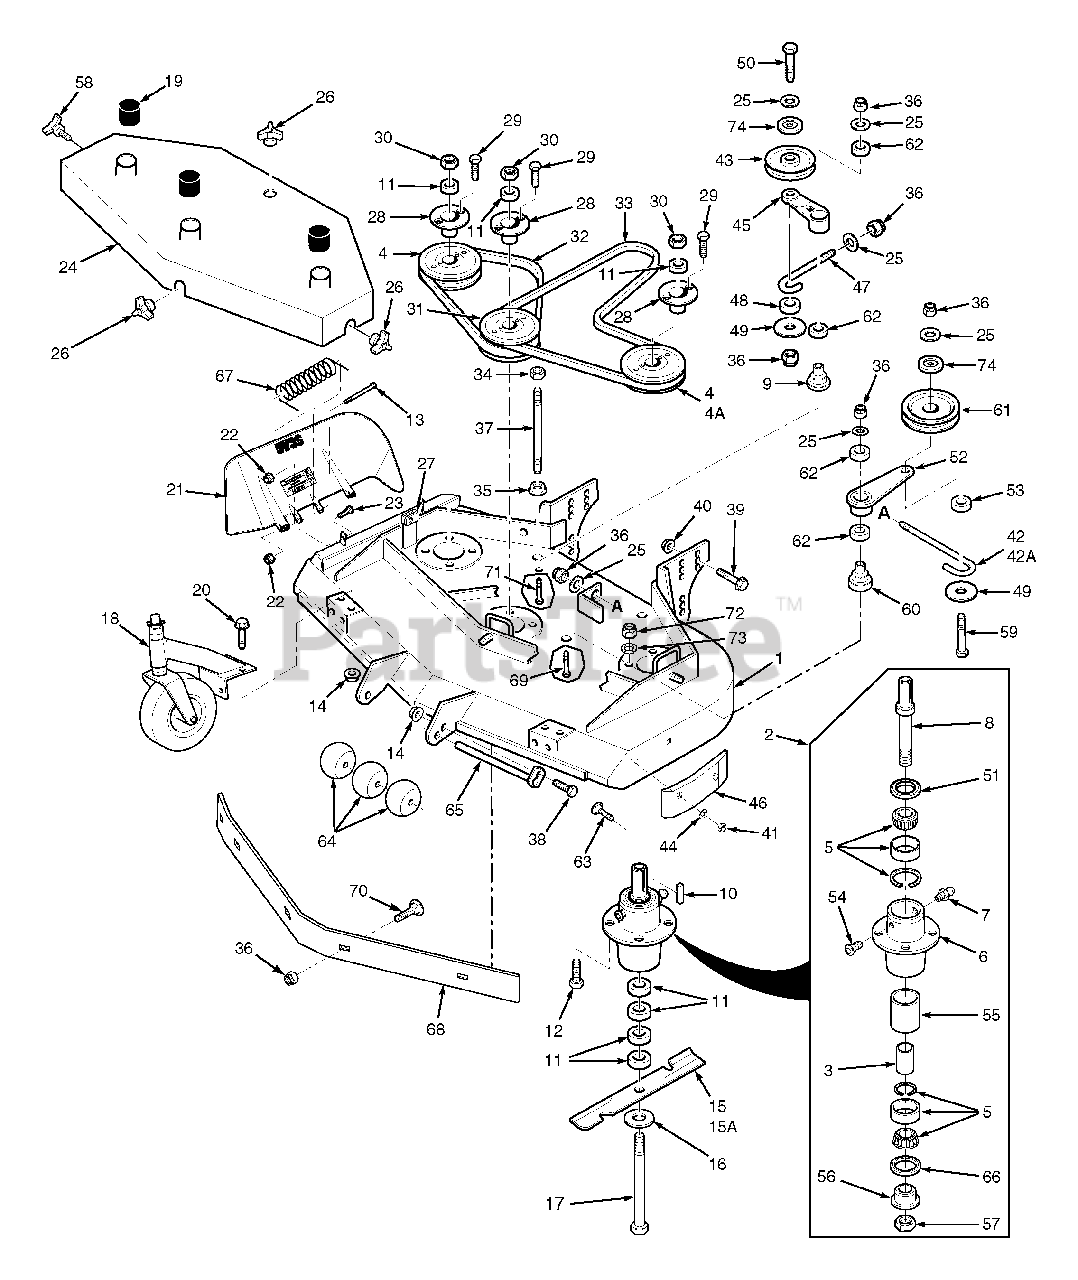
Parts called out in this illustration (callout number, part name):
1	Cutter Deck
2	Spindle Assembly
3	Spacer, Inside
4	Pulley, 5.75" OD
4A	Pulley, 6.35" OD
5	Tapered Bearing (Two)
6	Spindle Housing
7	Grease Fitting Str. 5/16
8	Spindle Shaft, Tapered Brng
9	Idler Pivot
10	Key, 1/4 x 1/4 x 2"
11	Spacer, Cutter Blade - Small
12	Bolt, 5/16-18 x 1-1/2" Hex Head Gr 8
13	Bolt, 5/16-18 x 4-3/4" Hex Head
14	Serrated Flange Nut, 5/16-18
15	Cutter Blade 18"
15A	Cutter Blade 18" Hi Lift
16	Flatwasher,5/8" (.688 x 1.75 x .134)
17	Hex Head Bolt, 5/8-11 x 9-1/2"
18	Caster Assembly
19	Spindle Shield
20	Capscrew, 5/16-18 x 3/4"
21	Discharge Chute
22	Nut, 5/16-18 Elastic Elastic Stop
23	Bolt, 5/16-18 x 1-1/2" Hex Head
24	Belt Cover
25	Flat Washer, 3/8" Special
26	Wing Nut, 3/8-16 (Large)
27	U-Nut, 3/8-16
28	Tapered Hub
29	Bolt, 1/4-20 x 1" Hex Head
30	Nut, 5/8-11 Hex
31	Pulley, Double
32	Belt, RH Blade Drive
33	Belt, Blade Drive
34	Nut, 3/8-16, Nut Centerlock
35	Nut, 3/8-16, Serrated Flange
36	Nut, 3/8-16 Elastic Stop
37	Support, Belt Cover
38	Bolt, 5/16-18 x 1" Hex Head
39	Cpscrw,1/2-13 x 1"Ser Flng Hex Hd
40	Nut, 1/2-13 Spiralock
41	Hex Nut, 5/16-18 Center Locknut
42	J-Hook
42A	J-Hook
43	Idler Pulley, "V" Groove
44	Flatwasher, 5/16"
45	Idler Arm Assy.
46	Pad, Deck Wear
47	J-Rod, Idler Pulley
48	Spacer, J-Rod
49	Washer, 3/8 x 1-1/2 x 16 ga.
50	Bolt, 3/8-16 x 2-1/2" Hex Head
51	Seal, Cutter Spindle
52	Idler Arm Assy
53	Spacer, J-Rod
54	Relief Fitting, Cutter Spindle
55	Spacer, Outside, Cutter Spindle
56	Spindle Bushing
57	Nut, Cutter Spindle
58	Knob, w/stud
59	Bolt, 3/8-16 x 3-3/4" Hex Head
60	Idler Pivot
61	Idler Pulley, Belt Clutch
62	Bearing
63	Bolt, Carriage 5/16-18 x 3/4"
64	Guide Roller
65	Roller Shaft
66	Seal, Cutter Spindle
67	Spring, Chute Return
68	Baffle Weldment 52V
69	Bolt, 3/8-16 x 3-1/4" Hex Head
70	Bolt, Carriage 3/8-16 x 1"
71	Bolt, 3/8-16 x 2-3/4"
72	Nut, Hex Lock 5/16-18
73	Lock Washer 5/16
74	Dust Shield
